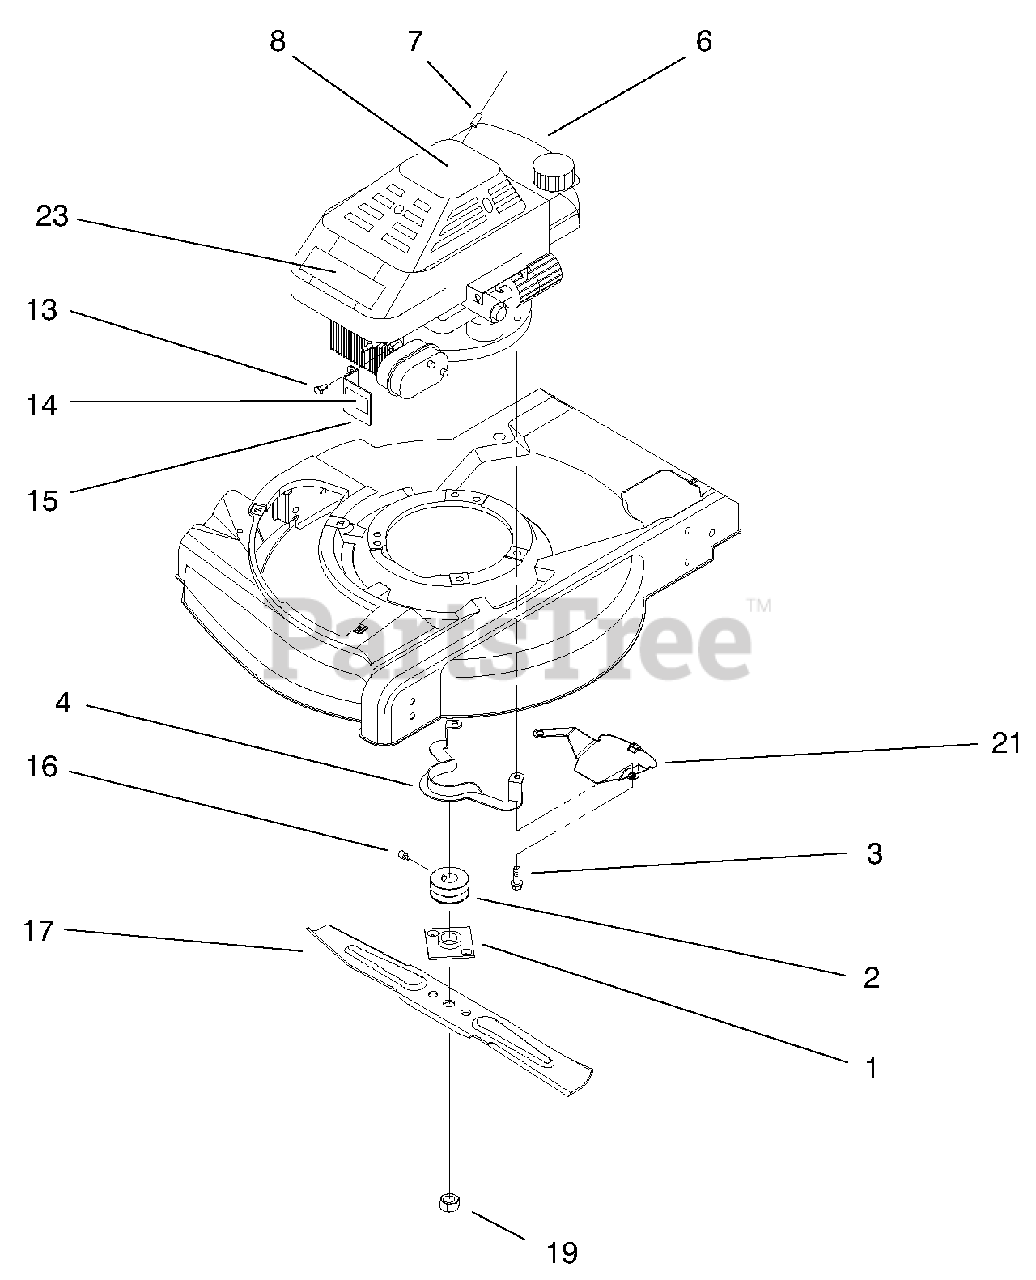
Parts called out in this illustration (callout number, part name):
1	ASM-Plate & Collar
2	Pulley-Engine
3	Screw-Engine Mount
4	Guide-Belt
6	ASM-Engine
7	Rope-Stop
8	Decal-Shroud Top
14	Decal-Hot Surface
15	Guard-Muffler
16	Screw-Set
17	Blade-21" Whirl
19	Nut-Blade
21	Shield-Grass
23	Applique
